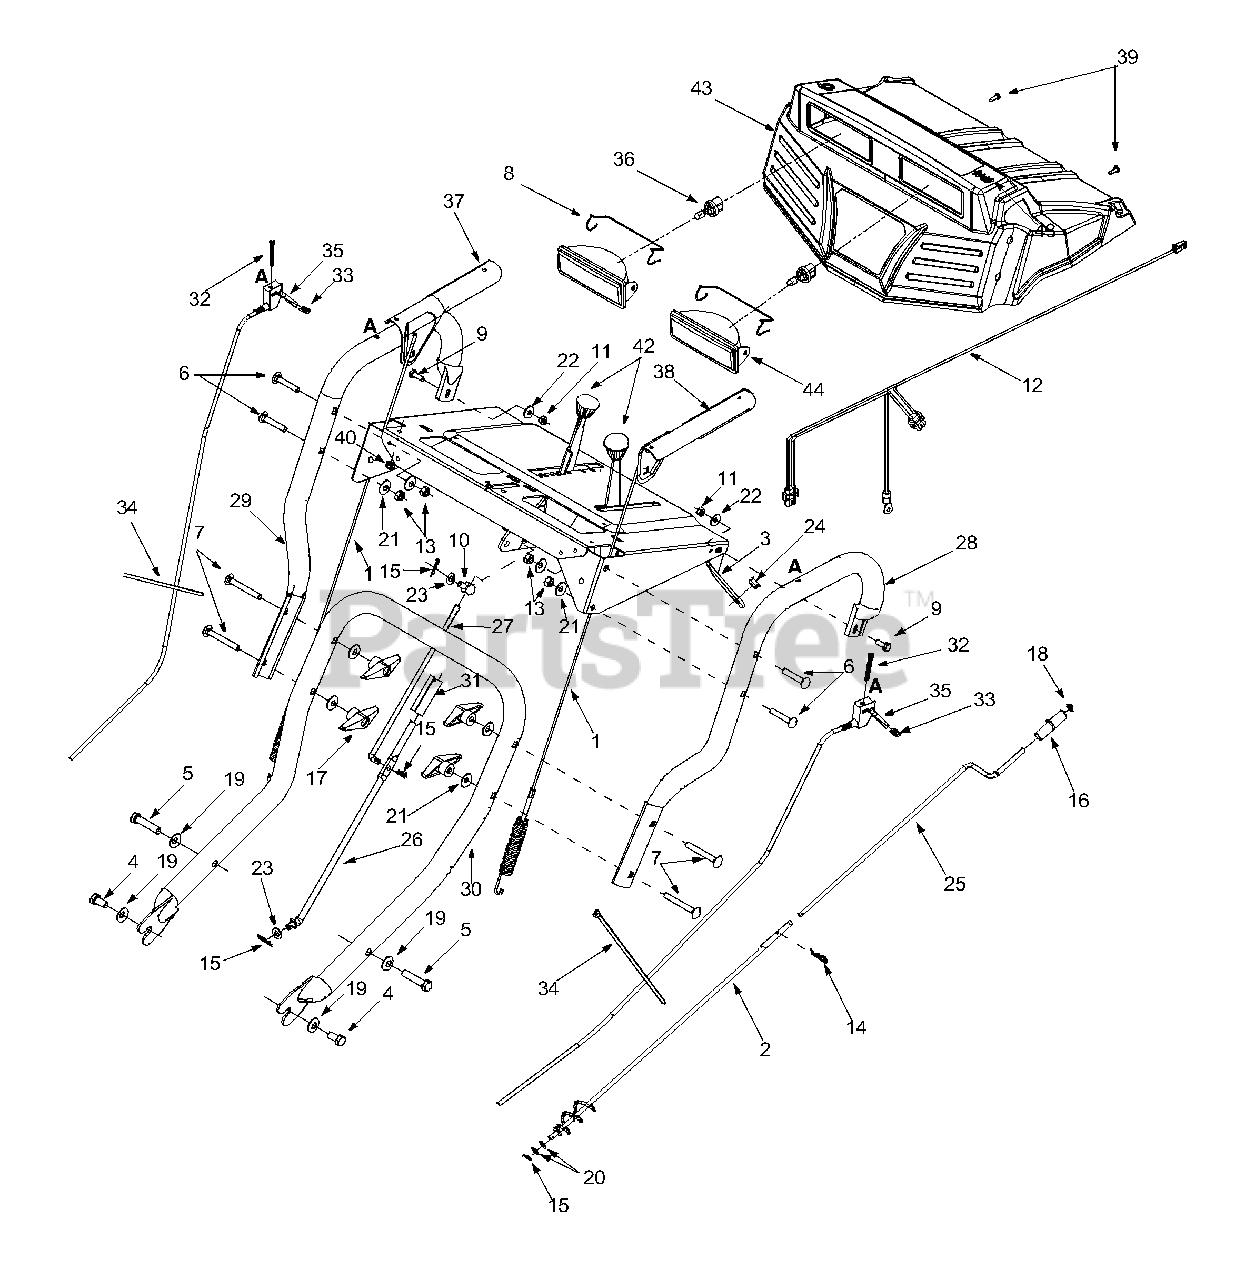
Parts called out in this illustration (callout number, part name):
1	Cable Assembly, Auger/Drive
4	Hex Screw, 3/8-16 x .88"
5	Hex Screw, 3/8-16 x 1.75"
6	Carriage Bolt 5/16-18 x 1.75"
7	Carriage Bolt 5/16-18 x 2.5"
8	Lamp Retainer
9	Hex Screw 1/4-20 x .75"
10	Ferrule
11	Hex Nut 1/4-20
12	Lamp Wire Harness
14	Hairpin Clip
15	Hairpin Clip
16	Chute Crank Knob
19	Bell Washer
20	Flat Washer
21	Beleville Washer
22	Bell Washer
23	Flat Washer
24	Plastic Bushing
26	Lower Shift Rod
27	Upper Shift Rod
31	Clutch Rod Connector
32	Oval C-Sunk Screw
33	Flat Weld Nut
34	Cable Tie
35	Trigger Control
36	Halogen Lamp
37	Handle Engagement RH
38	Handle Engagement LH
39	Special B Screw
40	Hex Sems Nut
42	Shift Knob
43	Handle Panel
44	Lens Assembly
